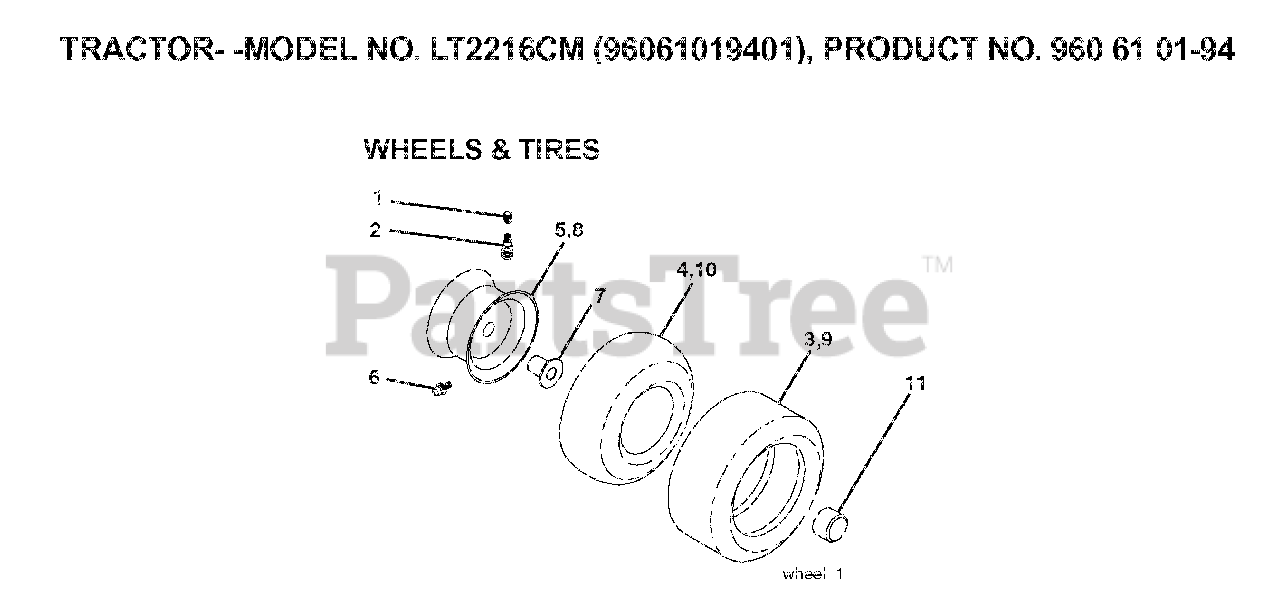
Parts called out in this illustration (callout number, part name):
1	VALVE CAP
2	VALVE STEM LT
3	TIRE HEAVY DUTY
4	TUBE.5.3/4.5/6
5	RIM ASM 6" FRONT SILVER
6	FITTING LT
7	BEARING T
8	RIM ASM 8" REAR SILVER
9	TIRE HEAVY DUTY
10	TUBE
11	CAP, AXLE BLK
